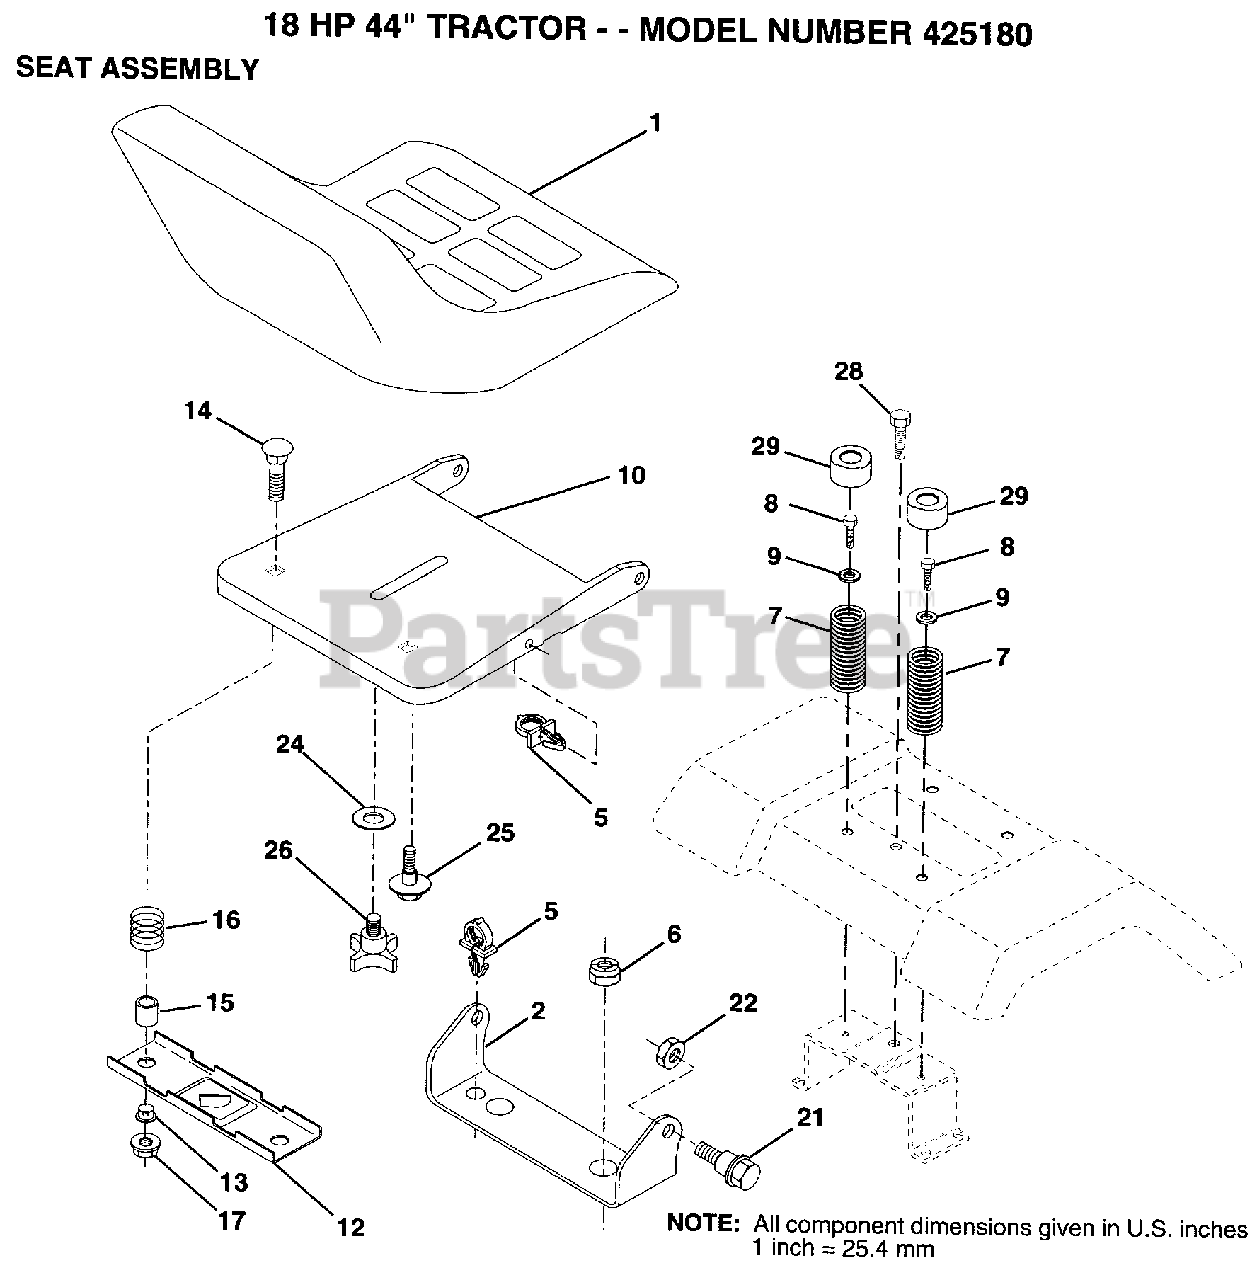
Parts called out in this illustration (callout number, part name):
2	BRACKET PVT SEAT
5	CLIP PUSH - IN
7	SPRING COMPRESSIO
8	SCREW LT
9	WASHER
12	BRKT SWITCH
13	BUSHING
15	SPACER SPLIT
16	SPRING COMPRESSED
21	BOLT.SHLD.5/16-18
24	WASHER
25	"BOLT,SHOULDER"
26	"KNOB 1/2"" YT"
28	SCREW LT
29	CAP SPRING
